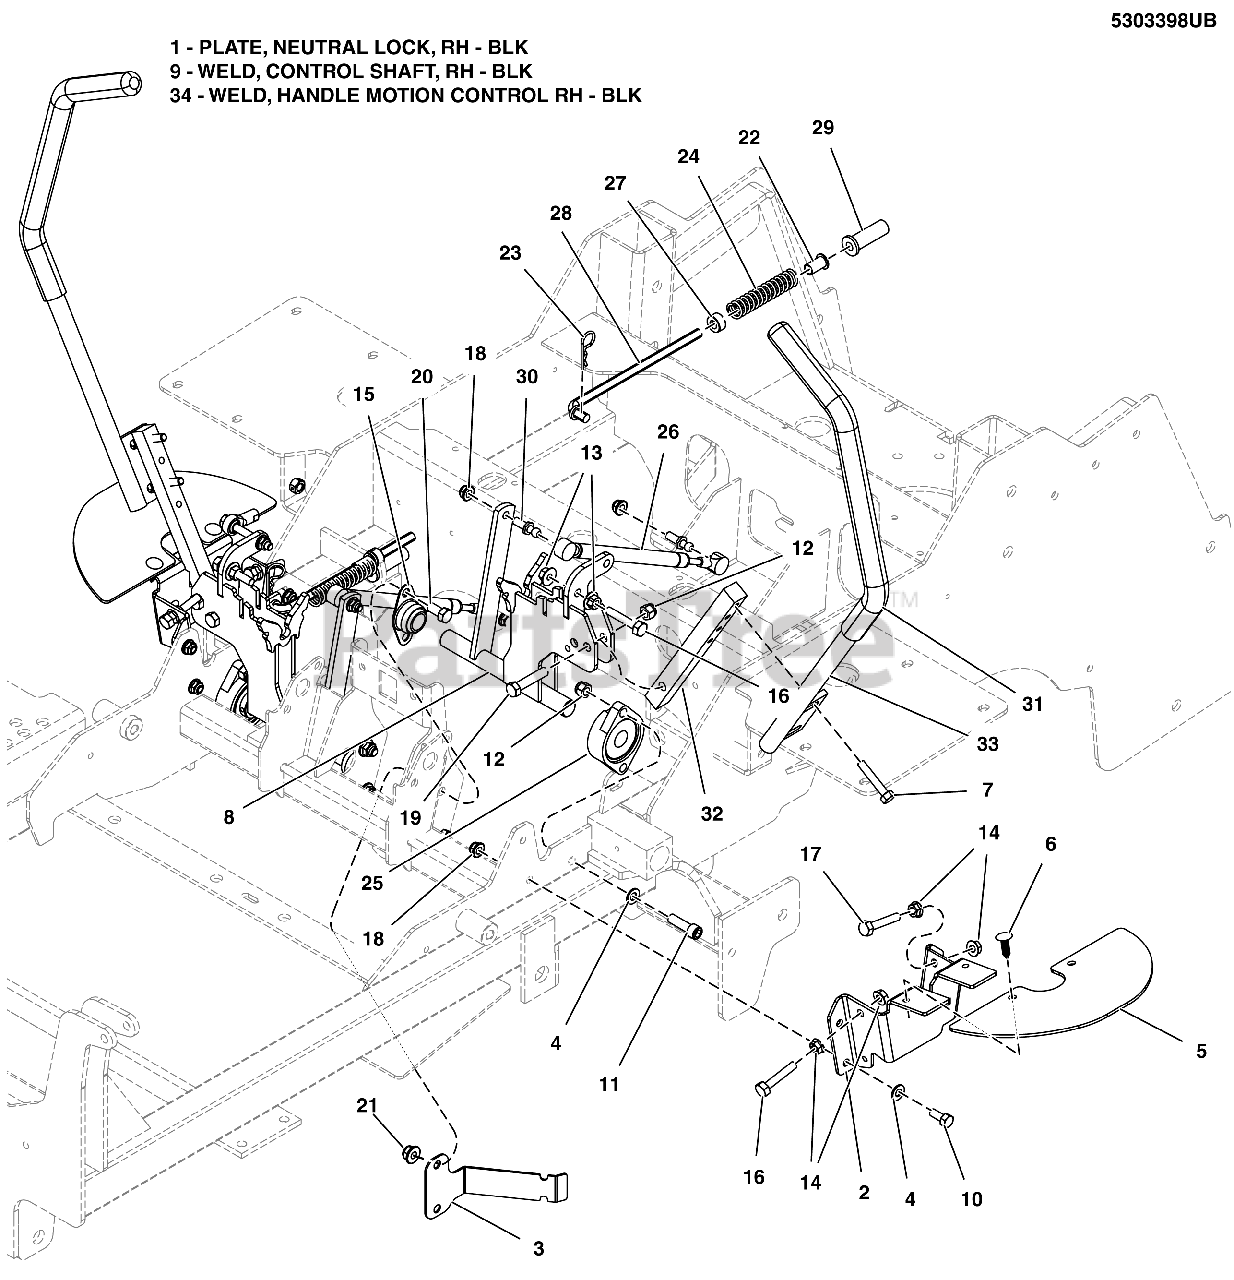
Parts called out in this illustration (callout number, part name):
1	PLATE, Neutral Lock, RH - BLK
2	PLATE, Neutral Lock, LH - BLK
3	BRACKET, HARNESS MOUNT, 2100 - BLK
4	WASHER, 5/16" SAE
5	GUARD, RUBBER MOTION CONTROLS
6	PUSH RIVET (TREE TYPE), BLACK
7	SCREW, 5/16-18x0.750, GR5, WHIZ-LOCK, ZC
8	WELD, CONTROL SHAFT, LOCKOUT, LH - BLK
9	WELD, CONTROL SHAFT, LOCKOUT, RH - BLK
10	BOLT, 5/16-18 X 3/4 GD5
11	BOLT, Allen Head, 3/8-16 x 1-1/4
12	NUT, 3/8-16 HEX NYLON LOCK
13	NUT, 5/16-18 HEX SERRATED FLANGE (LARGE)
14	NUT, 5/16-18 HEX SERRATED FLANGE (SMALL)
15	BEARING, BRONZE FLANGE, 3/4"
16	BOLT, 5/16-18 X 1-1/4 GD5 TFL, CZ
17	BOLT, 5/16-18 X 1-3/4 TFL, GD5 YZ
18	NUT, 5/16-18 HEX NYLOCK FLANGE NUT
19	BOLT, 3/8-16 X 1-3/4" GD5 CZ
20	BOLT, 3/8-16 X 3/4" GD5 CZ
21	NUT, 3/8 - 16 HEX NYLOCK FLANGE
22	BUSHING, FLANGE 3/8ID X 7/8 LONG
23	3/32 X 1-5/8 HAIR PIN CLIP
24	SPRING, REVERSE RETURN
25	BEARING, FLANGE
26	DAMPENER, CONTROL,#(P6709/P3610)
27	COLLAR, 3/8" Set
28	ROD, NEUTRAL RETURN, CZ
29	FLANGED BUSHING, 3/8IDX.63ODX.8125FL
30	10MM BALL STUD, 5/16-18 X 3/4 THDS
31	GRIP, FOAM, 1" ID, 16" LONG
32	MOUNT, CONTROL ARM - BLK
33	WELD, HANDLE MOTION CNTRL, 19.0, 1.0, LH - BLK
34	WELD, HANDLE MOTION CNTRL, 19.0, 1.0, RH - BLK
